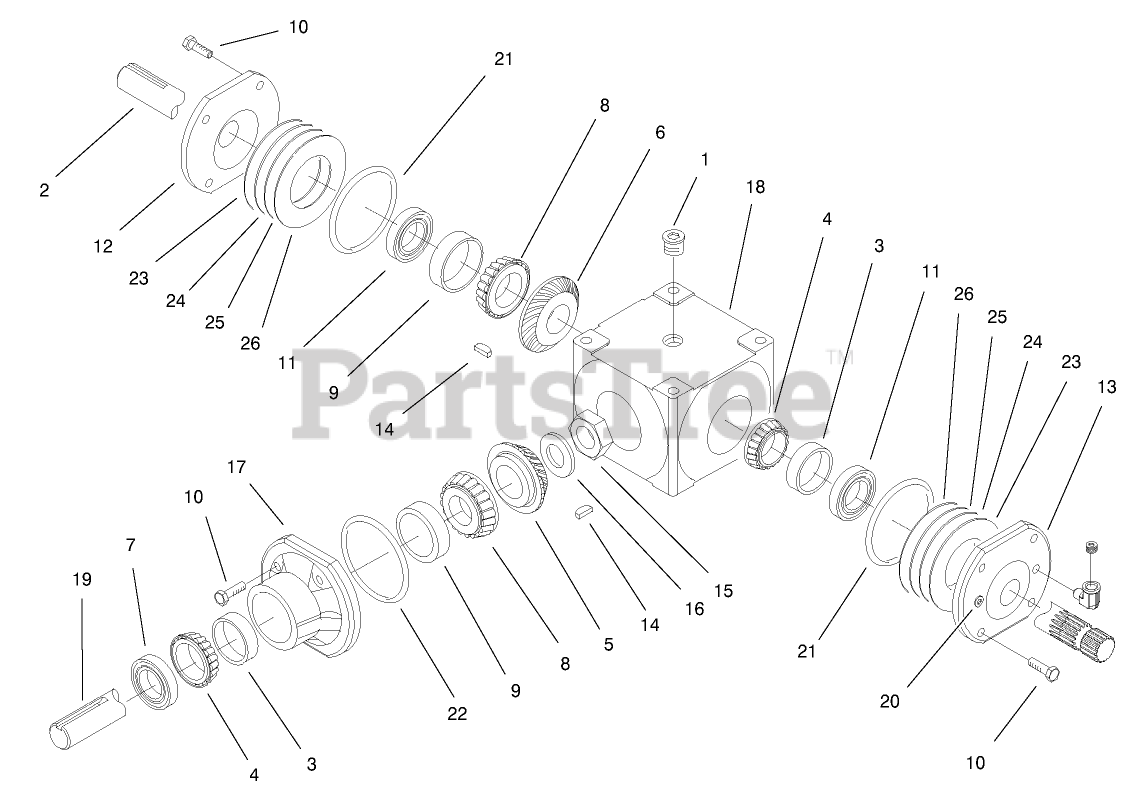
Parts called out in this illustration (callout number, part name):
2	SHAFT-CROSS
3	Bearing-Cup
4	Bearing-Cone
5	Gear-Spiral,RH
6	Gear-Spiral,LH
8	BEARING-CONE
9	BEARING-CUP
10	SCREW-HH
11	SEAL
12	CAP-END
13	END CAP W/ DRAIN PLUGS
14	OBS KEY
15	NUT-JAM
17	Pinion Housing
19	Shaft-Pinion
21	O-RING
23	SHIM-GREEN (.003)
24	SHIM-BLUE (.005)
25	SHIM - BROWN (.010)
26	SHIM-YELLOW (.020IN)
